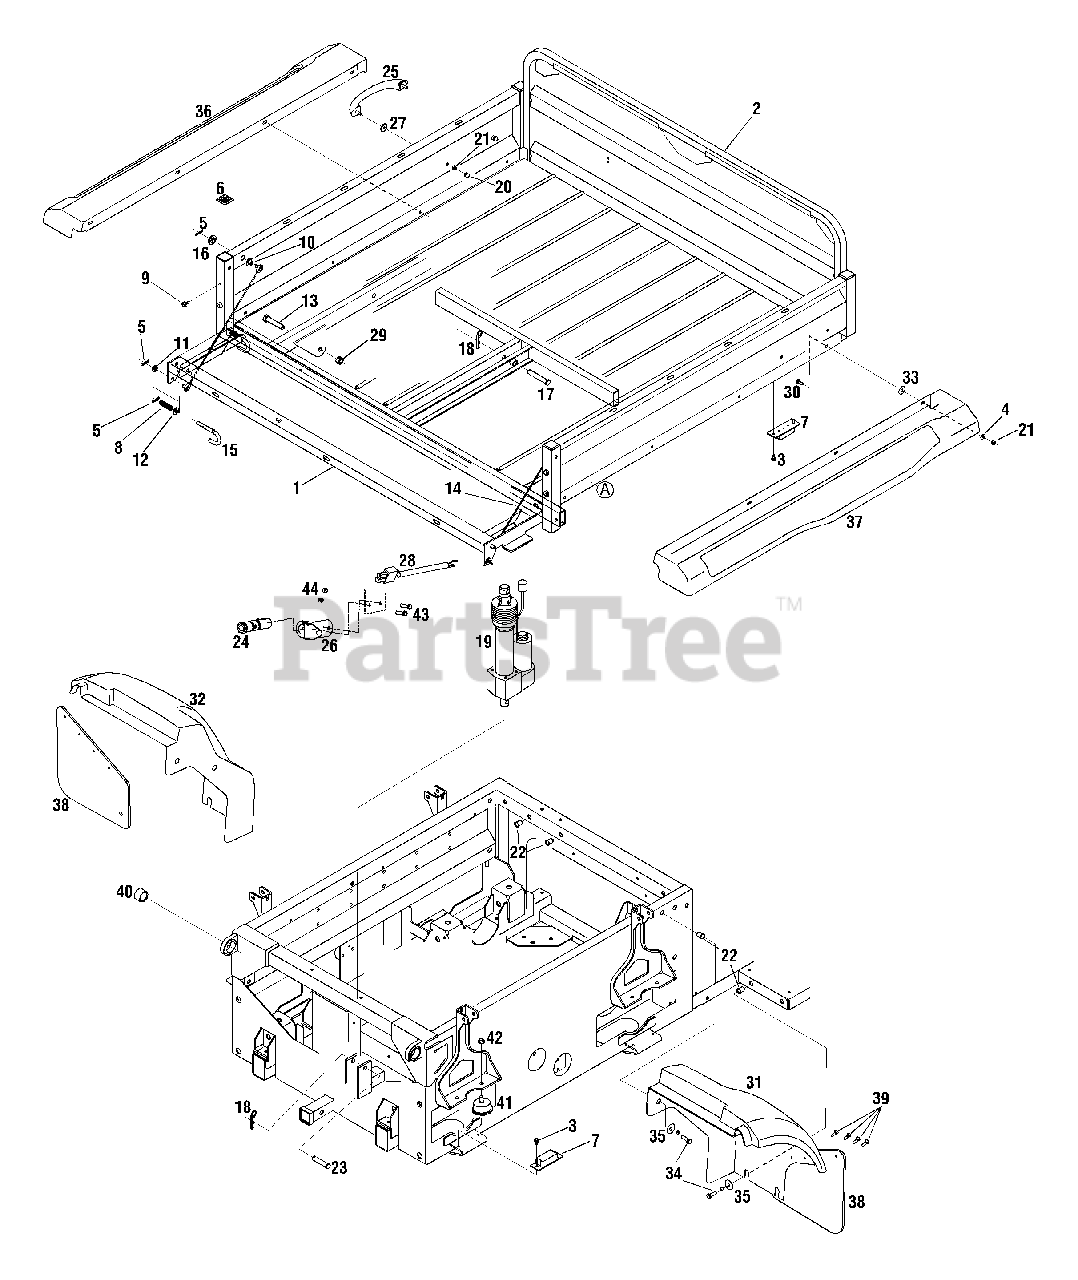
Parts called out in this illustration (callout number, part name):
1	Tailgate Assembly
2	Bed Assembly
3	Screw, Self-tapping, 1/4-20 x 0.500
4	Flat Washer,.271 x.630 x.065
5	Cotter Pin,.072 Dia x 1.13
7	Bumper, Extension Suspension
8	Compression Spring, .406 x .531 x
9	Bumper, .62Dia x .3
10	Washer, Flat, .64 ID x 1.0 x .12
11	Washer, Flat, .344 x .750 x .120
12	Washer, Flat,.407 x.812 x.135
13	Screw, Hex, 1/2-13 x 2.5
14	Cable, LIft 16.16 LG
15	Handle, Deck Release
16	Spacer, Shoulder .625 Dia x .324 Dia
17	Clevis Pin,.5 x 3.0 Lng.
18	Cotter Pin
19	Electric Actuator, 6" Stroke
20	Nut, Acorn 1/4-20 w/o Lock
21	Nut, Hex Lock, 1/4-20
22	Nut, Insert 5/16-18
23	Clevis Pin,.5 x 2.25 Lng.
24	Plug Receptacle, 12V/15A
25	Handle, Bag w/Screw
26	Power Receptacle, 12V/15A
27	Washer, Flat .265 x .938 x .120
28	Harness Jumper
29	Hex Lock Nut, 1/2-13
30	Hex Screw, 1/4-20 x.75
31	Fender, Rear RH, Red
32	Fender, Rear LH, Red
33	Rubber Washer,.310 x 1.0 x.125
34	Hex Screw, 5/16-18 x 1.0
35	Bell Washer,.39 x 1.38 x.062
36	Bed Skirt Panel, LH, Red
37	Bed Skirt Panel, RH, Red
38	Rear Mud Flap
39	Pop Rivet,.188
40	Rubber Bushing, Bed Pivot
41	Bumper, Compression Suspension
42	Hex Lock Nut, M10-1.25
43	Screw, #10-24 x.500
44	Hex Nut, 10-24
